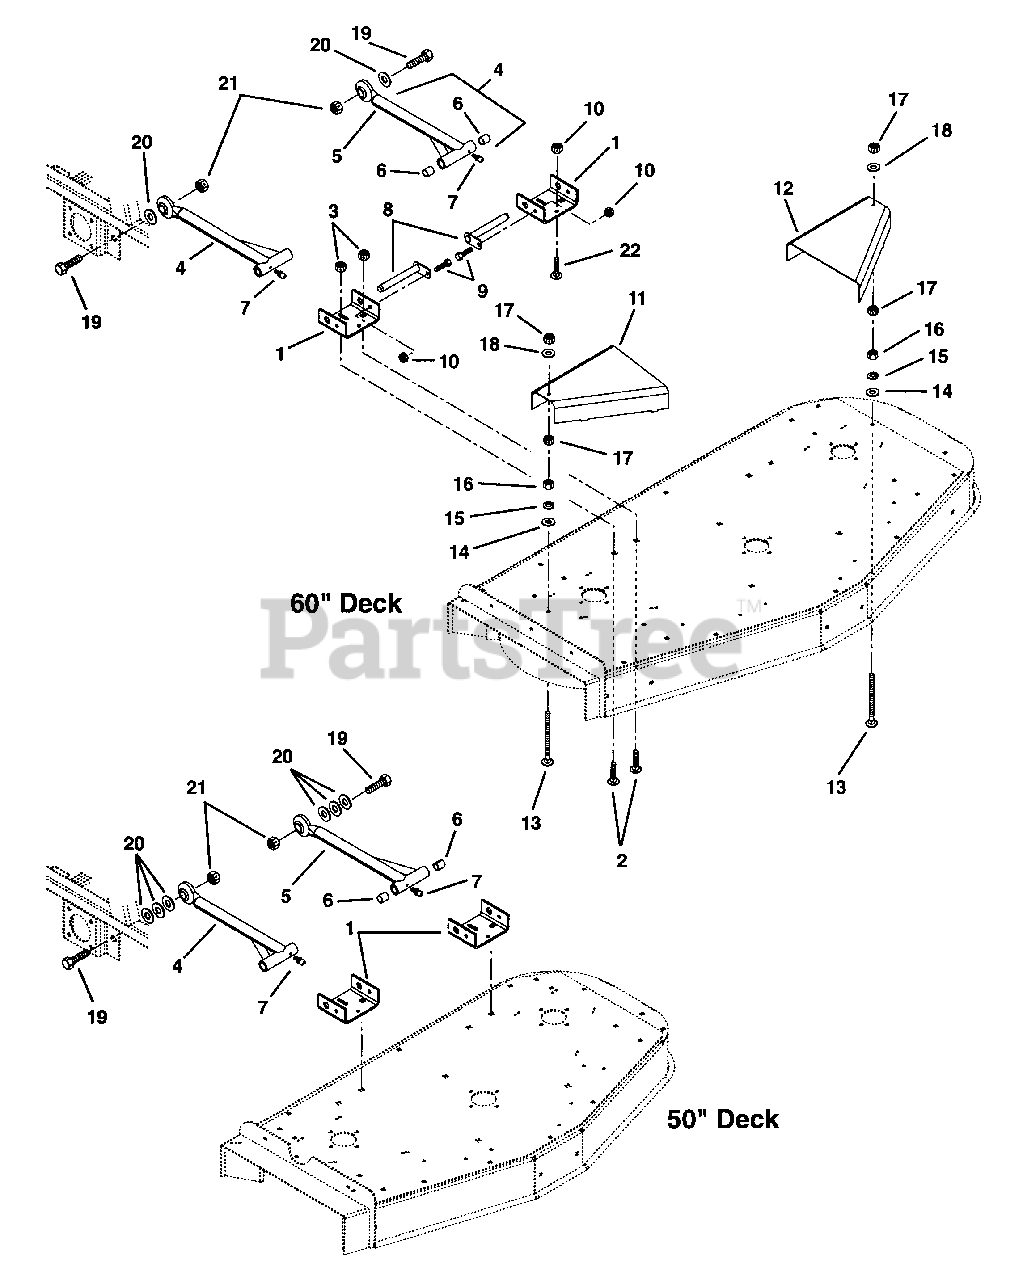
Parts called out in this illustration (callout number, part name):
1	Bracket, Mower Mounting (Rear)
2	Bolt-Round Head Square Neck .50-13 x 1.00 Grade 2
3	Nut-Locking-Center .50-13
4	Assembly, Mower Mounting Arm
5	Weldment-Mower Mounting Arm
6	Bearing .75 x .875 x 1.00
7	Fitting-Lube .25-28 x .256
8	Weldment, Mower Mounting Pin
9	Bolt-Hex .38-16 x .75 Grade 5
10	Nut-Locking-Center .38-16
11	Guard, Pulley Right Hand (60" Deck)
11	Guard, Pulley Right Hand (50" Deck)
12	Guard, Pulley Left Hand (60" Deck)
12	Guard, Pulley Left Hand (50" Deck)
13	Bolt-Round Head Square Neck .31-18 x 3.50
14	Washer-Flat-Steel .344 x .688 x .065
15	Washer-Locking .31 x .078
16	Nut-Hex .31-18
17	Nut-Locking-Center .31-18
18	Washer-Flat-Steel .438 x 1.00 x.083
19	Bolt-Hex .875-9 x 2.75 Grade 5
20	Washer-Flat-Steel .875 x 1.500 x .1196 60" Deck
21	Nut-Locking-Center .875-9
22	Bolt-Round Head Square Neck .38-16 x 1.00 Grade 5
